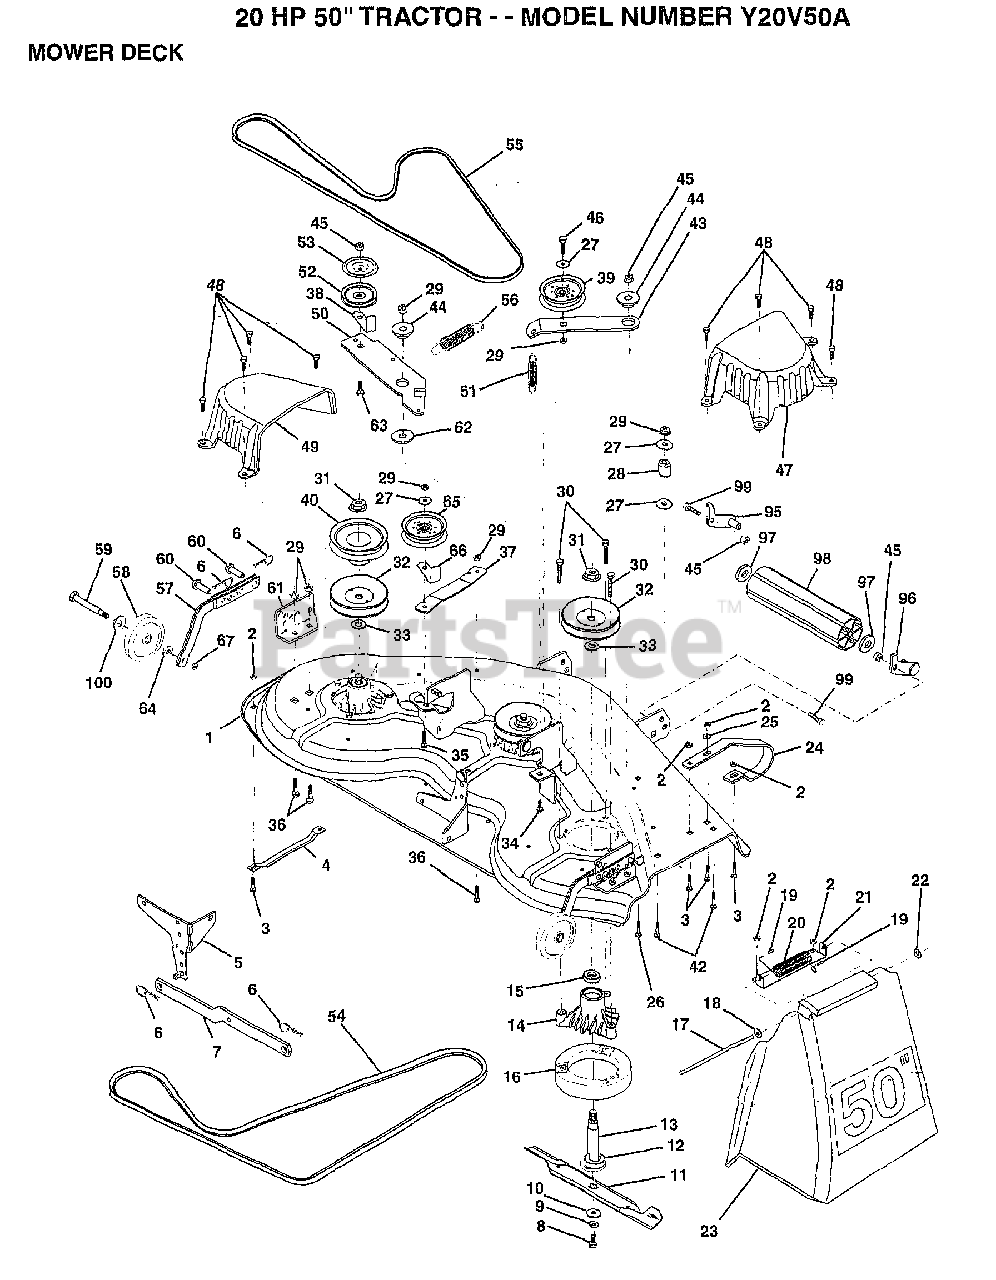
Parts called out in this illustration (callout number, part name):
1	DECK ASM MWR 50VT
2	NUT
4	RUNNER-LH M
5	BRKT.ASM.SW.44/50
8	BLADE BOLT
10	WASHER.HARD.BLADE
11	"BLADE.50"" HD"
12	BEARING.BALL
13	SHAFT.ASM.W/BRNG
14	HOUSING.MAND.44.V
15	BEARING
16	STRIPPER RND MWR
17	ROD-HINGE T
18	WASHER
19	CAP-SLEEVE LT
20	SPRING TORSION
21	BRKT DEFLECTOR
22	NUT PUSH M
23	DEFLECTOR
24	"RUNNER RH 50"" DK"
25	WASHER M
26	BOLT
27	WASHER
29	NUT
33	WASHER
34	BOLT.3/8-14X1.25
35	BOLT
36	BOLT D
37	STIFFENER.ARM.IDL
39	FLAT IDLER PULLEY
40	"PULLEY.DRIVEN.44"""
42	BOLT
43	"ARM.IDLER.SEC.44"""
44	SPACER RETAINER
47	"COVER.MAND.RH.44"""
48	SCREW.1/4-20X5/8
49	COVER.MANDREL.LH
50	ARM.IDLER.PRIMARY
51	"SPRING.SEC.44""VEN"
52	PULLEY.IDLER.VGRO
53	SHIELD.IDLER.44.V
54	BELT V PRIM 50
55	BELT.V.GDRIVE.95
56	SPRING.EXT.DECK.
57	BAR.ASM.GUAGE.WHL
58	WHEEL.GAGE.BLK.PL
59	BOLT M
60	PIN.CLEVIS
61	BRACKET.GUAGE.WHL
62	HARDENED WASHER
63	BOLT.3/8-16X1.50
64	WASHER
65	IDLER-FLAT T
67	LOCKNUT
97	WASHER
99	BOLT
100	WASHER
